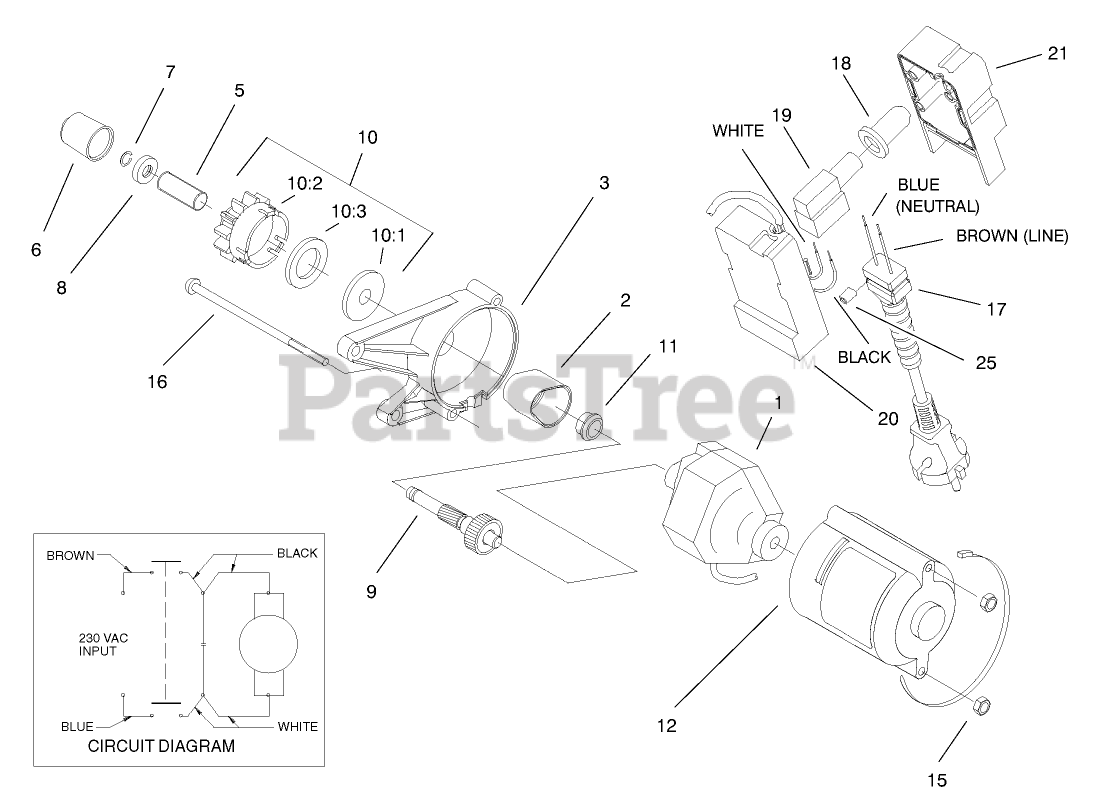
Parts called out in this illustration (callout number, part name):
2	COVER-GEAR
3	HOUSING-UPPER, STARTER
5	SPRING
6	CAP-PINION
7	RING-LOCK
8	STOP-PINION
10	PINION ASM
10:2	PINION
10:3	RING-RUBBER
11	BUSHING
12	HOUSING-LOWER, STARTER
15	NUT-LOCK, NI
17	PLUG-POWER 230 VOLT
18	BOOT-SWITCH
19	SWITCH-STARTER
20	SWITCH-BASE, HOUSING
21	HOUSING-CAP, SWITCH
